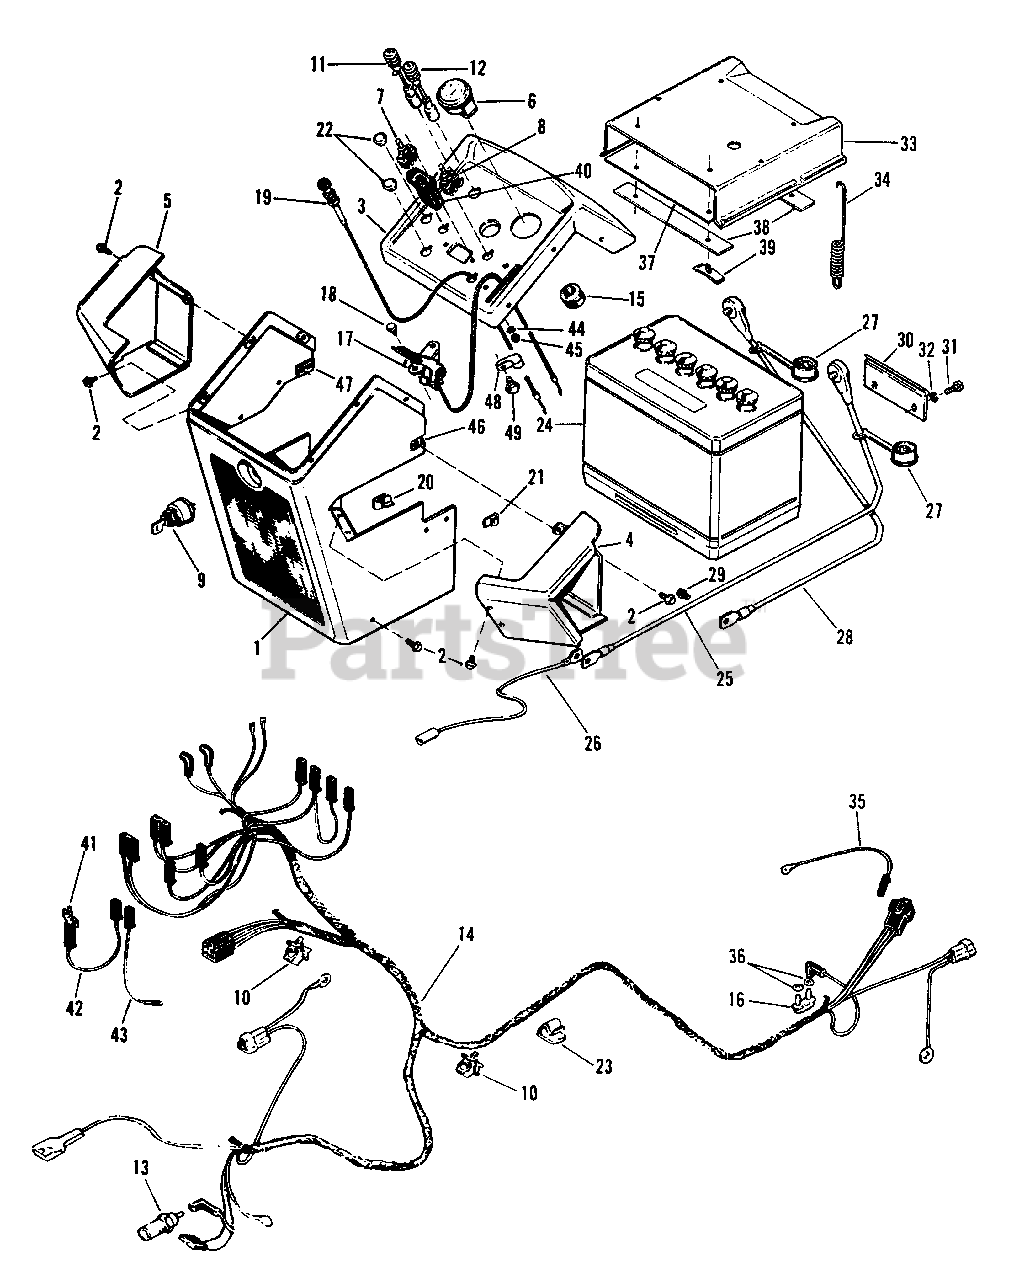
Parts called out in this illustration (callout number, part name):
1	Body Support Assy.
2	Thread Forming Screw, 1/4"-20 x 3/8" lg.
3	Panel Assembly
4	Panel Assembly, R.H.
5	Panel Assembly, L.H.
9	Ignition Switch
11	Indicator Light, Hot
12	Indicator Light, Oil
13	Indicator Light, Switch
14	Wiring Harness
16	Circuit Breaker
17	Throttle Control
18	Thread Forming Screw, 1/4"-20 x 5/8" lg.
19	Choke Control
21	Speed Clip
22	Plug Button
25	Cable, Positive
28	Cable, Negative
29	Taptite Screw, 5/16"-18 x 3/8" lg.
31	Hex Capscrew, 5/16"-18 x 3/4" lg.
32	Lockwasher, 5/16"
36	Paper Washer
39	Speed Clip
40	Hour Meter (Mfg. Nos. 953 & 954)
41	Two-Way Adaptor (Mfg. Nos. 953 & 954)
42	Wire (To Ignition Switch) (Mfg. Nos. 953 & 954)
43	Wire (To Ground) (Mfg. Nos. 953 & 954)
44	Lockwasher, External 1/4" (Mfg. Nos. 953 & 954)
45	Hex Nut, 1/4"-20 (Mfg. Nos. 953 & 954)
46	Speed Nut
47	Speed Nut
49	Screw Thread Form
